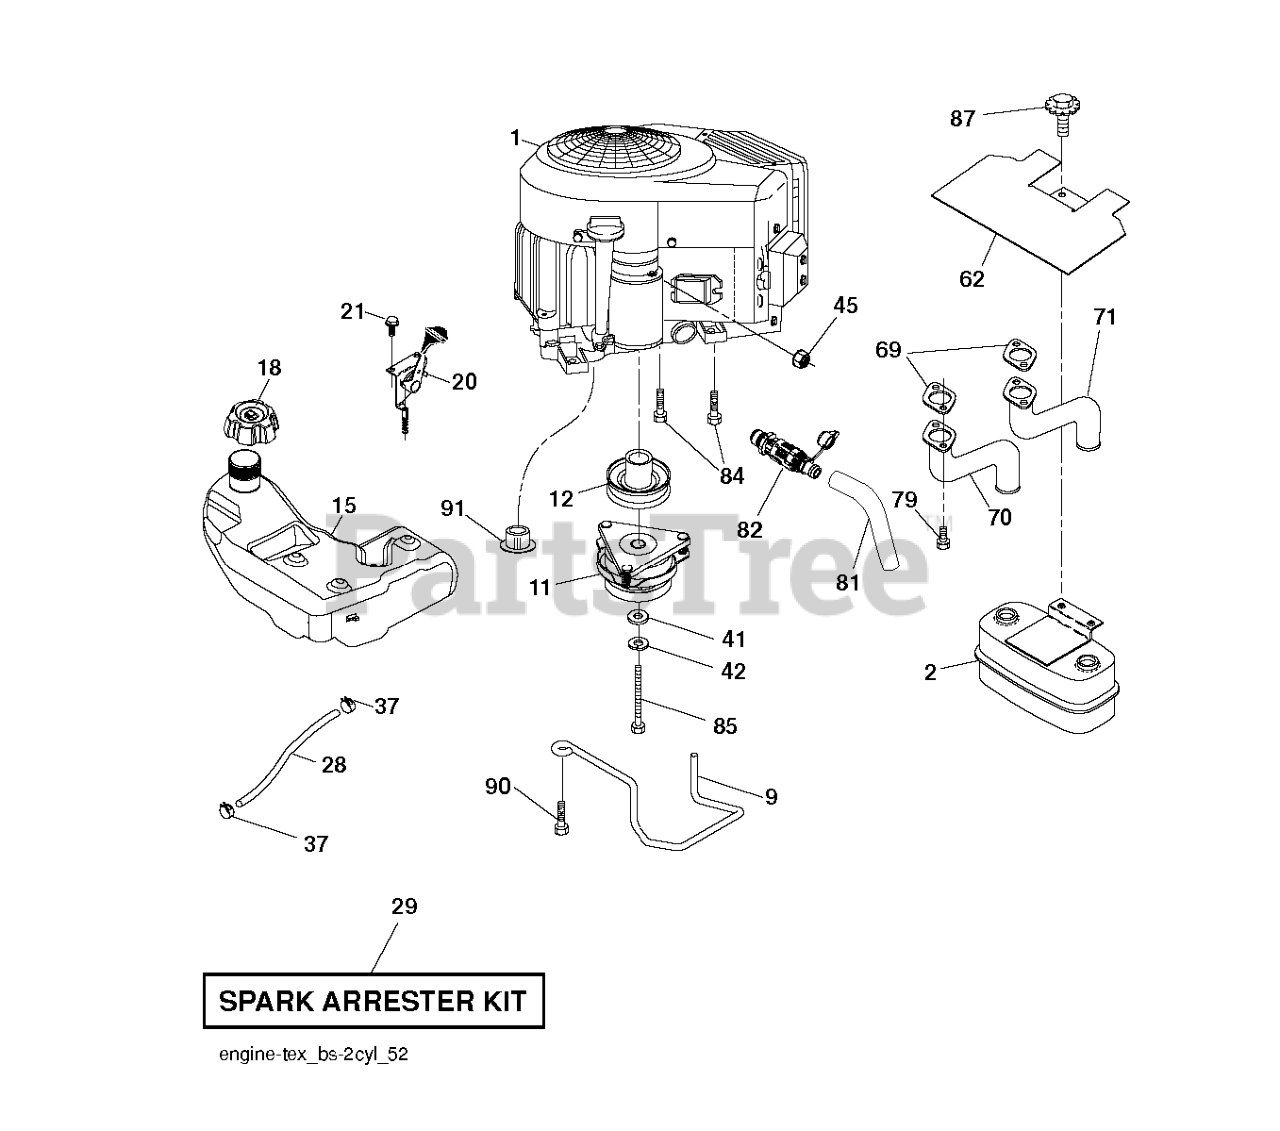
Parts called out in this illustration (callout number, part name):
2	MUFFLER.TWIN.CYL.LOW.TONE
9	KEEPER.BELT.ENGINE.4.2
11	CLUTCH.ELECTRIC.LT.48"*
12	PULLEY.ENGINE.TUFFTORQ
15	RP_TANK.ASSY.3.GAL.EPA
18	CAP.ASM.FL.RITCH.3"E10.SYM.498
20	CONTROL.TH/CK.COBRA.B&S.TWN.BK
21	SCREW.#10 X 0.750.BOS
28	LINE.FUEL.64"REAR.EMIS
29	KIT.SPARK ARRESTOR 794945 B&S
37	HOSE CLAMP
42	LOCKWASHER
45	NUT
62	SHIELD.HEAT.MUFFLER
69	GASKET.MUFFLER
70	RP.EXHAUST.TUBE.LH.BS/TWIN
71	EXHAUST.TUBE.RH.BS/TWIN
79	SCREW.SOCKET.HEAD.5/16-18
81	TUBE, DRAIN OIL ASM.
82	VALUE.OIL.DRAIN
84	SCREW.3/8-16
85	BOLT HEX 7/16-20X4-1/4"
87	BOLT.5/16-18UNCX3/4 W/SEMS.BLK
90	SCREW 3/8-16X1
91	BUSHING.1.375OD
